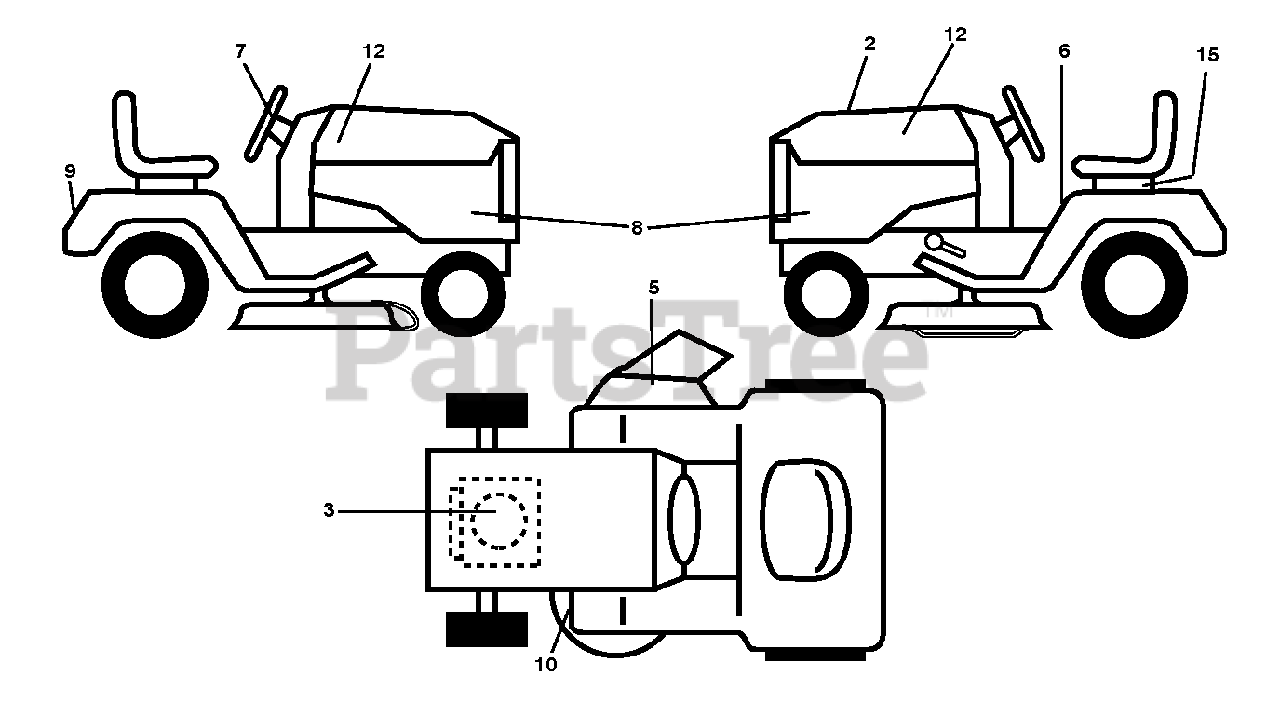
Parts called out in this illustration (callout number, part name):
2	DECAL.RPL.BSM31.INTK.TLW.42C
3	DECAL.ENG.BS.175INTK.
5	DECAL, DECK DEFLECTOR, WARNING
6	DECAL.FENDER.WARNING.ENGLISH
7	Decal, Steering Wheel STDXXSQ PPRO 2015
8	DECAL.SDPNL.PB175G42.BLK.PPRO
9	DECAL.REARFNDR.POULAN PRO.2015
10	DECAL.V-BELT.SCH.42/46"MEC/ELE
12	DECAL.POULAN PRO.2015
15	DECAL BTRY SYMBOLS
